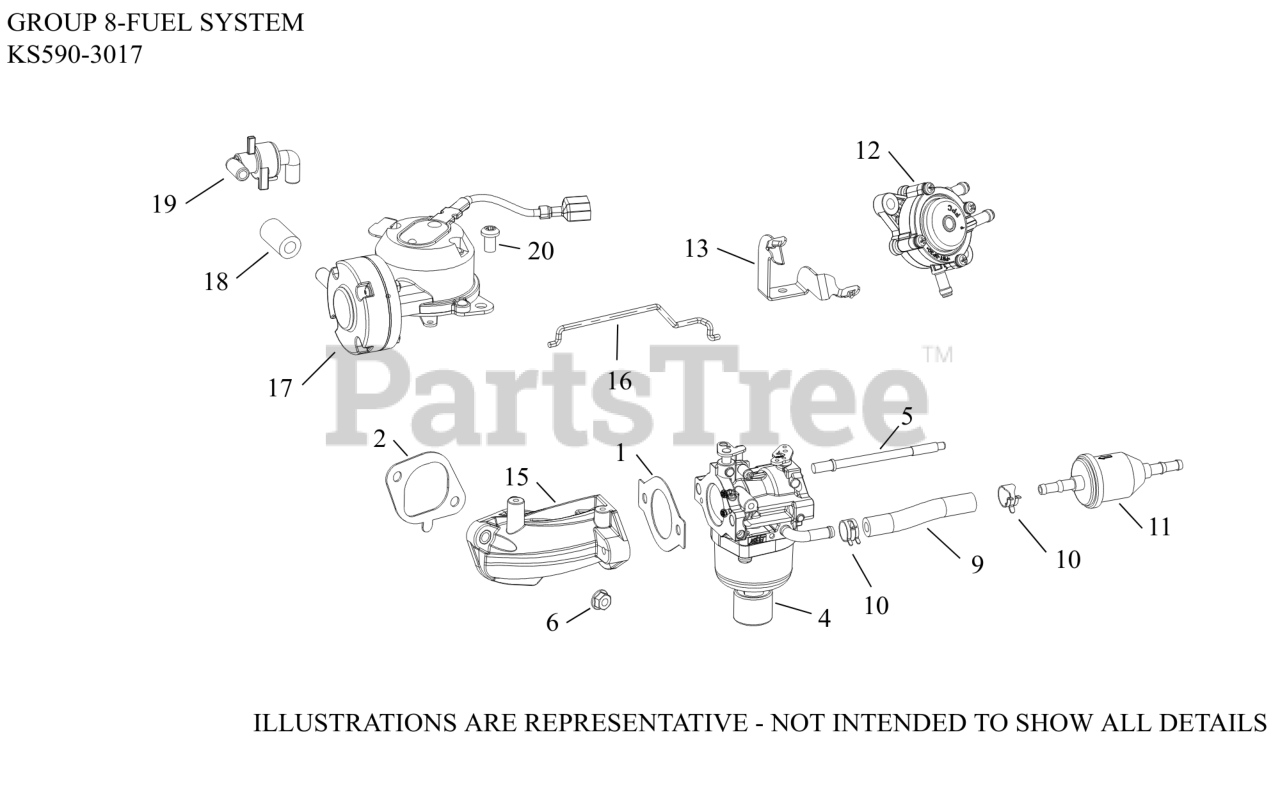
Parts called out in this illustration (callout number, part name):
1	GASKET, CARBURETOR (THROTTLE)
2	GASKET, INTAKE MANIFOLD
4	KIT,CARB(NIKKI)
5	STUD, CARBURETOR
6	NUT, FLG M6X1.0
9	HOSE,LW PERM.FUEL 24.00"-USE 25 111 81-S
10	SPRING CLAMP, HOSE
11	FILTER,FUEL 51 MICRON (FUEL PUMP)
12	PUMP, FUEL (PULSE)-(#2539326S)
13	BRACKET, FUEL PUMP
15	MANIFOLD, INTAKE ASSY
16	LINKAGE, CHOKE
17	DIAPHRAGM ASSY
18	HOSE, VACUUM
19	CHECK VALVE ASSY
20	SCREW, K40 X 1.79 TFS
NI	HIGH ALTITUDE KIT (5000 FT)
NI	KIT, OVERHAUL
NI	KIT, CHOKE SHAFT
NI	KIT, O-RING
NI	KIT, SOLENOID (NIKKI)
NI	KIT, BOWL WITH O-RINGS
NI	KIT, FLOAT & INLET NEEDLE FOR FUEL PUMP
NI	KIT, THROTTLE SHAFT
